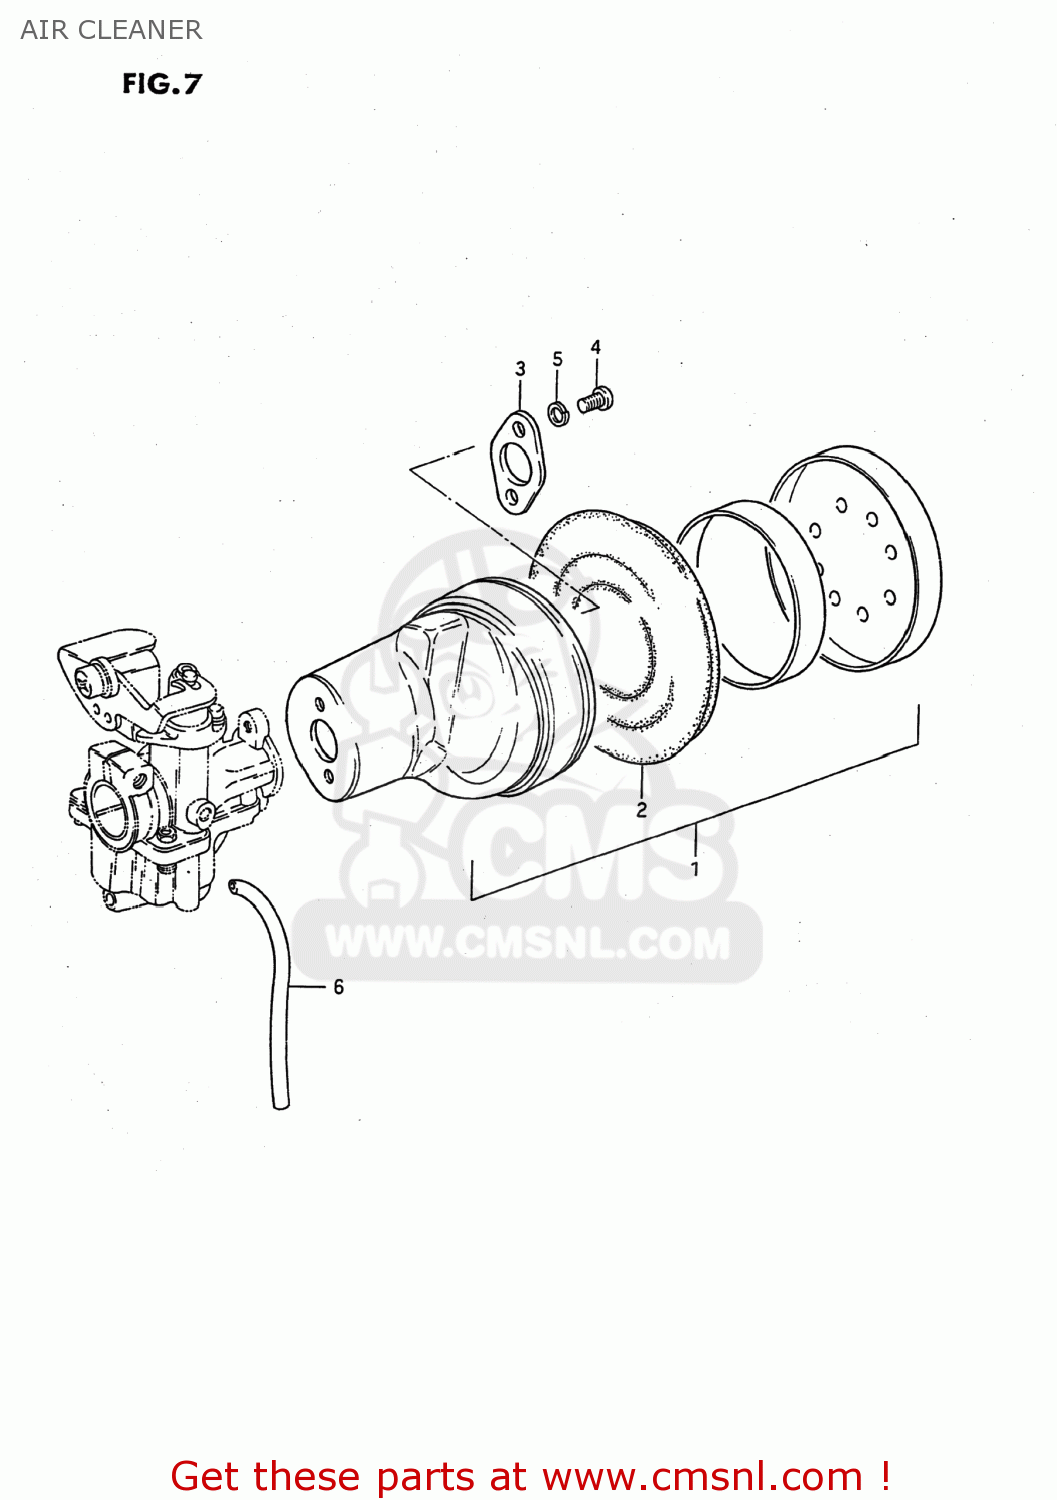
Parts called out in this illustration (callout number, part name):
1	CLEANER ASSY,AIR
2	FILTER,AIR CLEANER
3	PLATE,AIR CLEANER
4	SCREW
5	LOCK WASHER
6	HOSE
